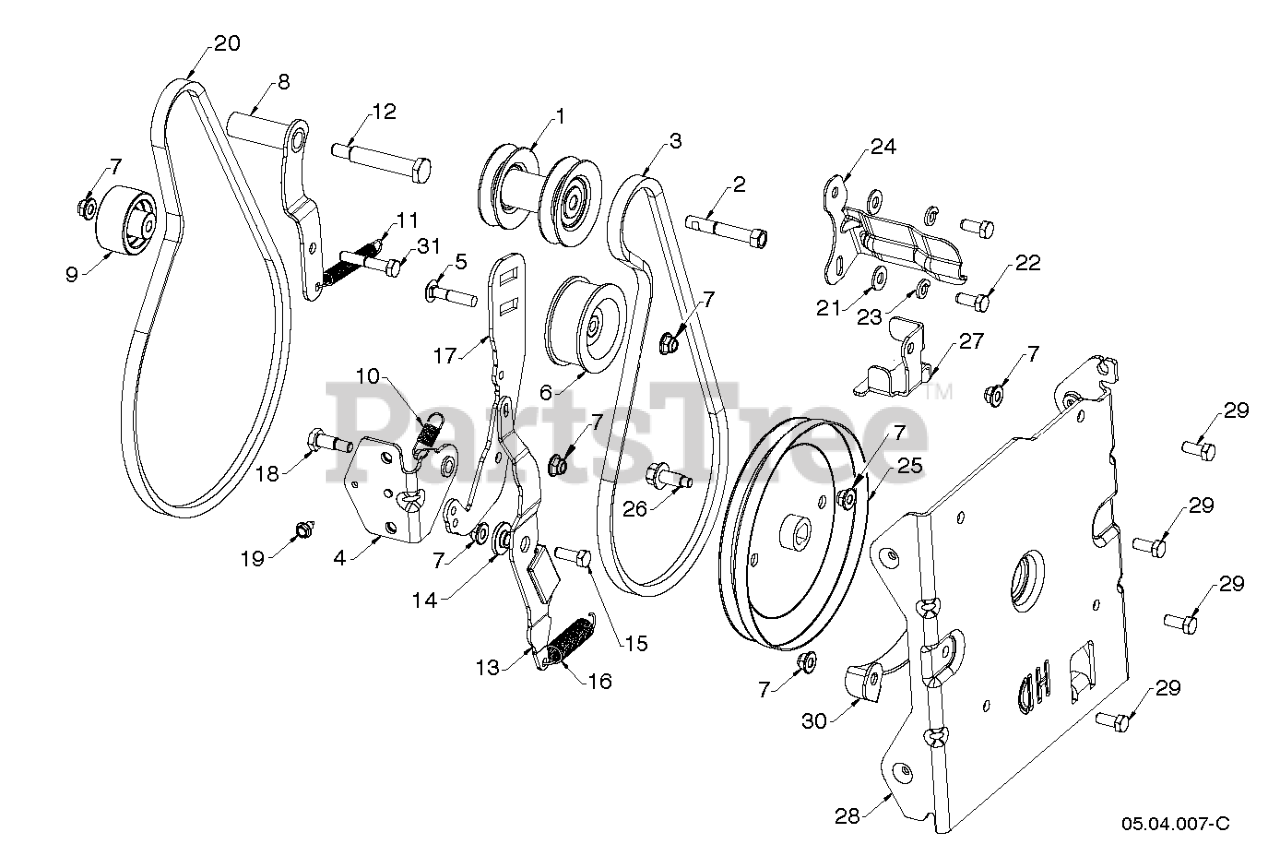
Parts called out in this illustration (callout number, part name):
1	PULLEY.ASM.IMPELLER/DRIVE
2	BOLT.ENGINE.PULLEY
3	LOW CRANK IMPELLER BELT
4	BRACKET WELDMENT, IDLER ARM ZI
5	BOLT 5/16-18 CARRIAGE 1.5L
7	NUT HEXAGON FLANGE 5/16-18 ST
8	ARM IDLER DRIVE WELDMENT_HOT
9	PULLEY.IDLER.FLNGLESS.W/SPACER
10	SPRING IDLER RETURN
11	SPRING RETURN IDLER ARM
12	BOLT 5/16-24X2.25 HEX HEAD SHO
13	ARM IMPELLER BRAKE
14	BUSHING.BRAKE.ARM
15	BOLT HEXAGON BOLT 5/16-18 X 7/
16	SPRING EXTENSION - BRAKE
17	ARM IDLER BLACK ZINC
18	SCREW HEX HEAD SHOULDER
20	BELT.DRIVE.SNOW.DUAL
21	WASHER 11/32 X 11/16 X 14 GA T
22	SCREW 5/16-24 X .75 GR5
23	WASHER SPRING LOCK WASHER WITH
24	BELT KEEPER BRACKET
25	PULLEY IMPELLER DD 4L HD
26	SCREW HEXAGON HEAD FLANGE 3/8-
27	GUIDE.LOWER.AUGER.BELT.479
28	BRACKET AUGER HOUSING INTERFAC
29	SCREW HEXAGON HEAD SCREW 5/16-
30	BRACKET.BELT.KEEPER.LOWER.BLAC
31	BOLT, HEX 5/16-18X1-3/4
